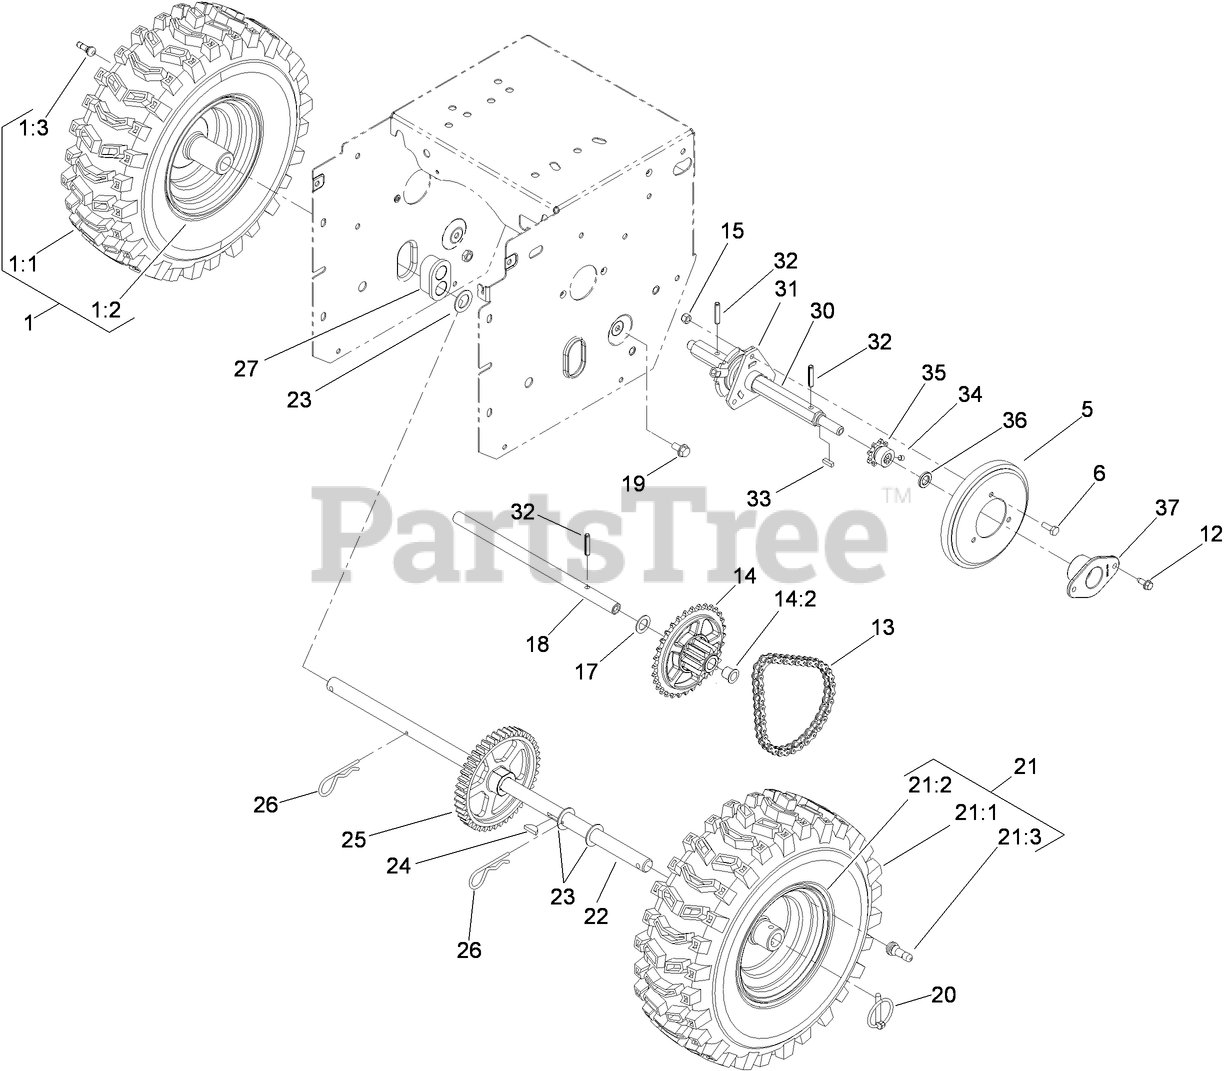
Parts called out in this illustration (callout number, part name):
1	Loose Parts Package
1:2	RIM-TIRE
5	WHEEL-FRICTION
6	SCREW-HH
12	SCREW-HWH
13	CHAIN-ROLLER
13	LINK-CONNECTING
14	SPROCKET ASM
14:2	BUSHING-FLANGE
15	NUT-LOCK, NI
17	WASHER-FLAT
18	SHAFT-INTERMEDIATE
19	SCREW-HWHTF
20	KLIK PIN ASM
21	Loose Parts Package
21:2	RIM-TIRE
22	SHAFT-AXLE
23	WASHER-THRUST
24	KEY-WOODRUFF
25	GEAR-AXLE, 44 TOOTH
26	PIN-HAIR
27	BEARING-AXLE
30	SHAFT-HEX
31	TRUNNION-HEX
32	PIN-ROLL, SLOTTED
33	KEY-SQUARE
34	SCREW-HSH
35	SPROCKET-8 TOOTH
36	SPACER-BUSHING
37	RETAINER-BEARING
